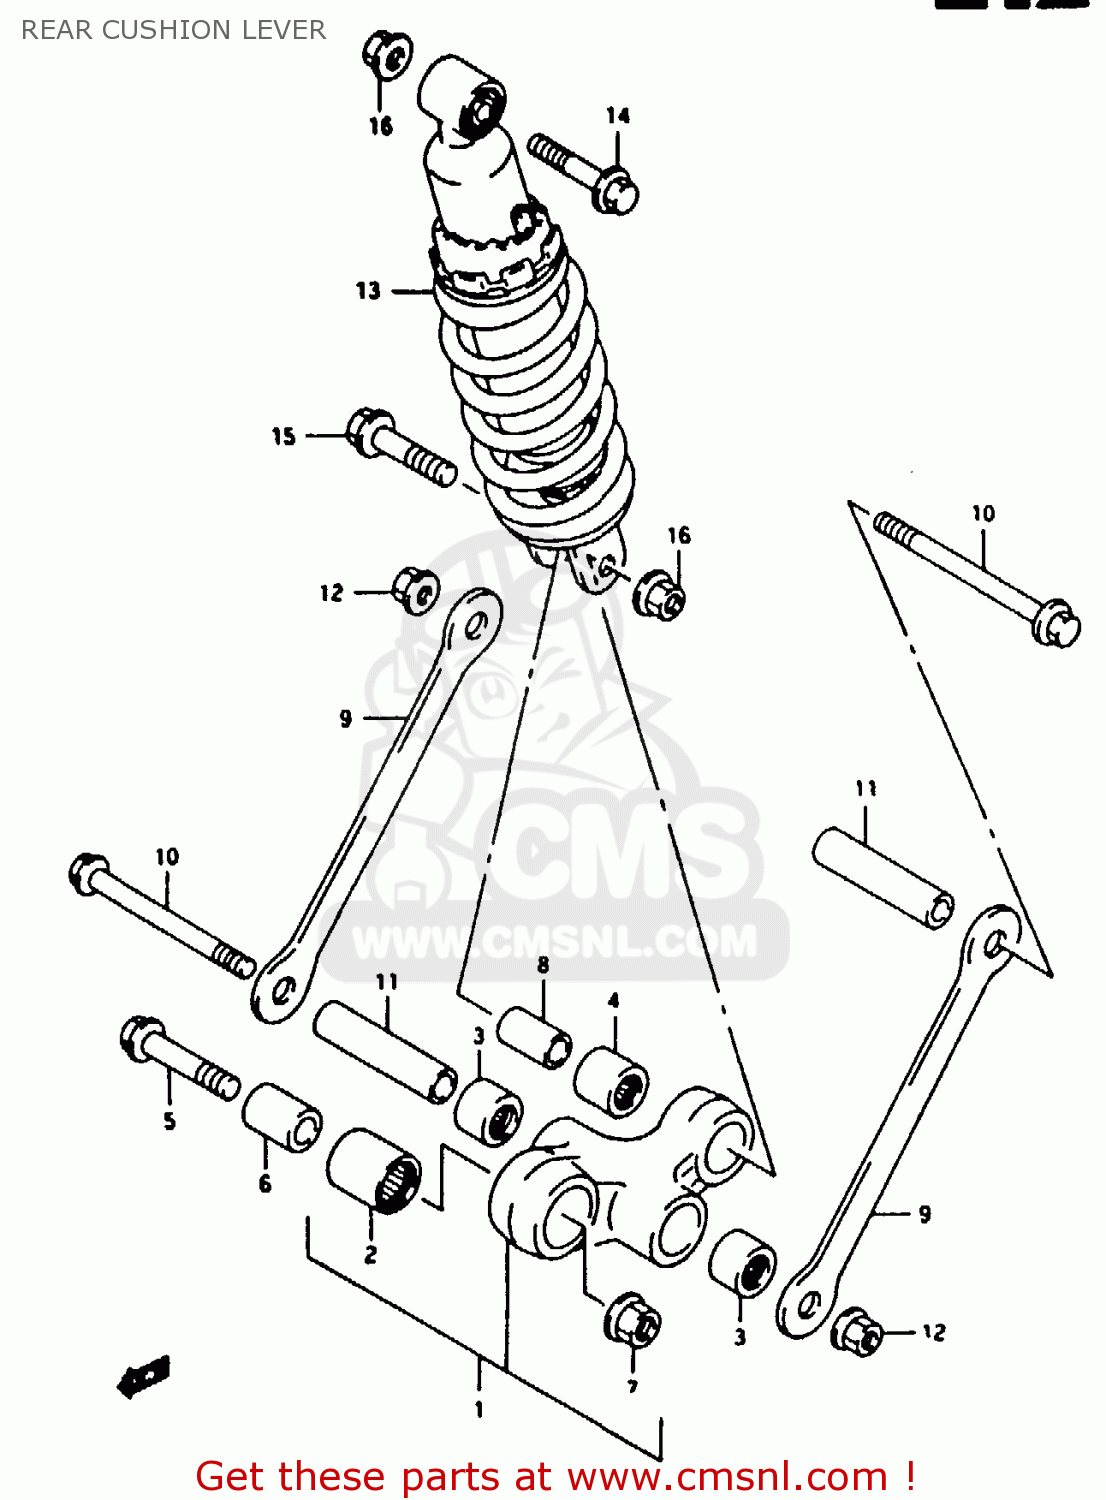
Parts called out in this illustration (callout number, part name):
1	LEVER SET, REAR CUSHION
2	BEARING(20X27X26)
3	BEARING(17X24X25)
4	BEARING(17X24X26)
5	BOLT, LEVER FRONT
6	SPACER,REAR CUSHION LEVER
7	NUT 12MM
8	SPACER,RR CUSHION LEVER
9	ROD, REAR CUSHION LEVER
10	BOLT,RR CUSHION ROD
11	SPACER(12X17X85)
12	NUT 12MM
13	ABSORBER ASSY,RR SHOCK
14	BOLT(10X50)
15	BOLT(10X52)
16	NUT
